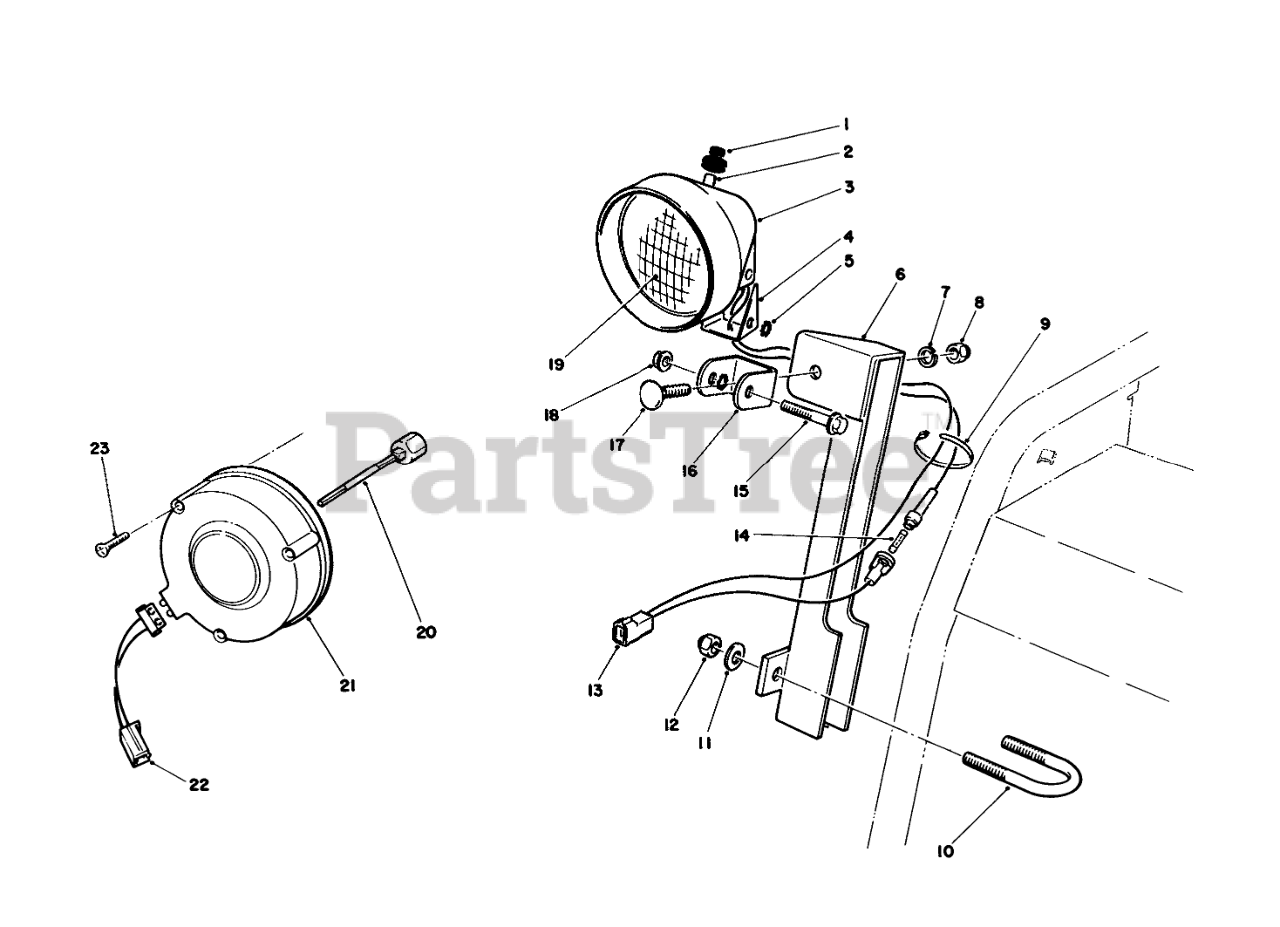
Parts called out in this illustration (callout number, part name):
1	BOOT-SWITCH
5	WASHER-LOCK
7	WASHER-LOCK
8	NUT-HEX
9	TIE-CABLE
10	U-BOLT
11	WASHER-PLAIN
12	NUT-LOCK, NI
13	WIRE ASM
14	Fuse-7-1/2 Amp.
15	SCREW-HH
17	BOLT-CARR
18	NUT-HF
19	BEAM-SEALED
21	TECUMSEH 1A183-69
